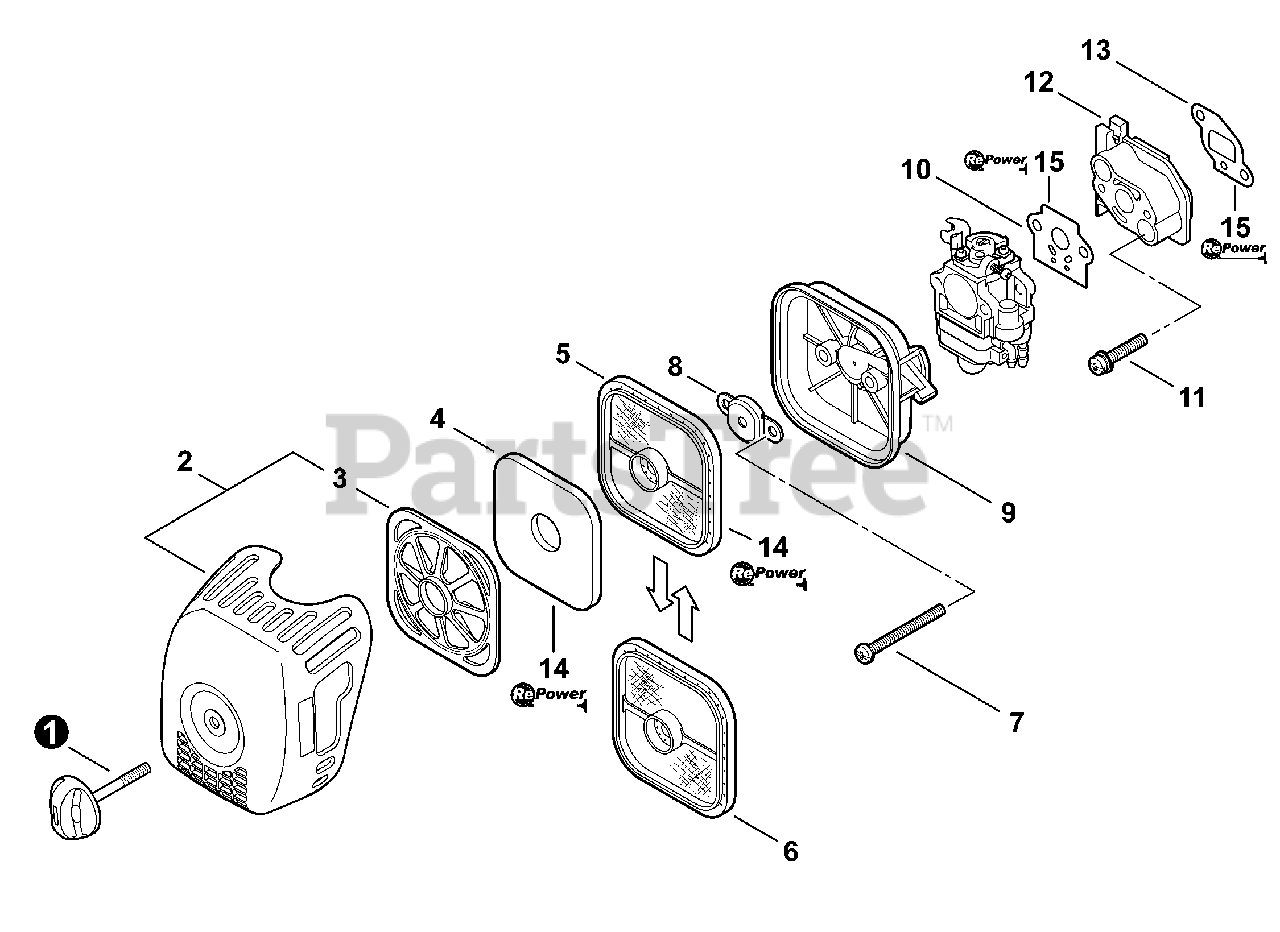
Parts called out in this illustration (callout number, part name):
1	THUMBSCREW
2	AIR CLEANER COVER KIT
3	RETAINER, PRE-FILTER
4	PRE-FILTER - FOAM
5	FILTER, AIR - DOUBLE LAYER
6	FILTER, AIR - SINGLE LAYER
7	SCREW - 5×60
8	PLATE, PREVENT
9	CASE, AIR CLEANER - BLACK
10	GASKET, INTAKE
11	SCREW - 5×30
12	INSULATOR
13	GASKET, INTAKE
14	TUNE-UP KIT - REPOWER
15	GASKET KIT - REPOWER
